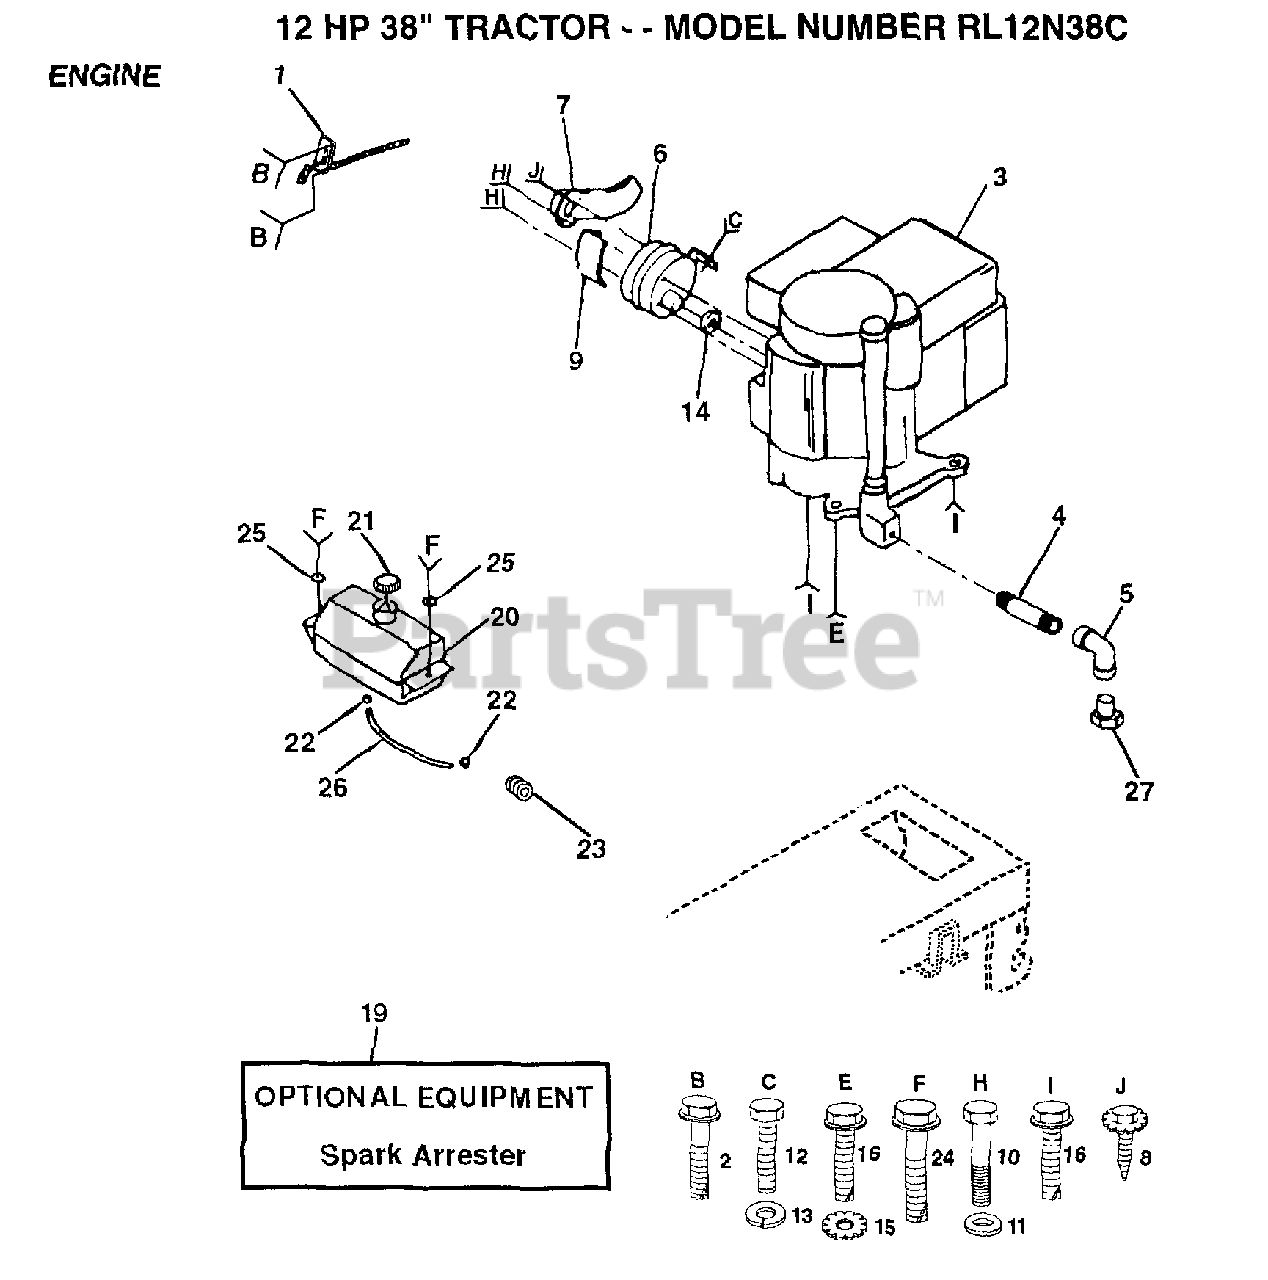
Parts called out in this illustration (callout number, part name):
1	THROTTLE CONTROL
2	SCREW LT
3	ENG B&S 10-12.5HP PWRBLT DC
4	PIPE NIPPLE
5	ELBOW
6	MUFFLER LTV
7	DEFLECTOR MUFFLER
9	SHIELD HEAT LTV
10	"BOLT,HEX"
11	WASHER T
12	BOLT
13	LOCKWASHER
15	LOCKWASHER
16	SCREW
20	TANK.FUEL.LT.
21	CAP ASM FUEL
22	HOSE CLAMP
24	SCREW HEX CRT
25	WASHER
26	LINE FUEL
